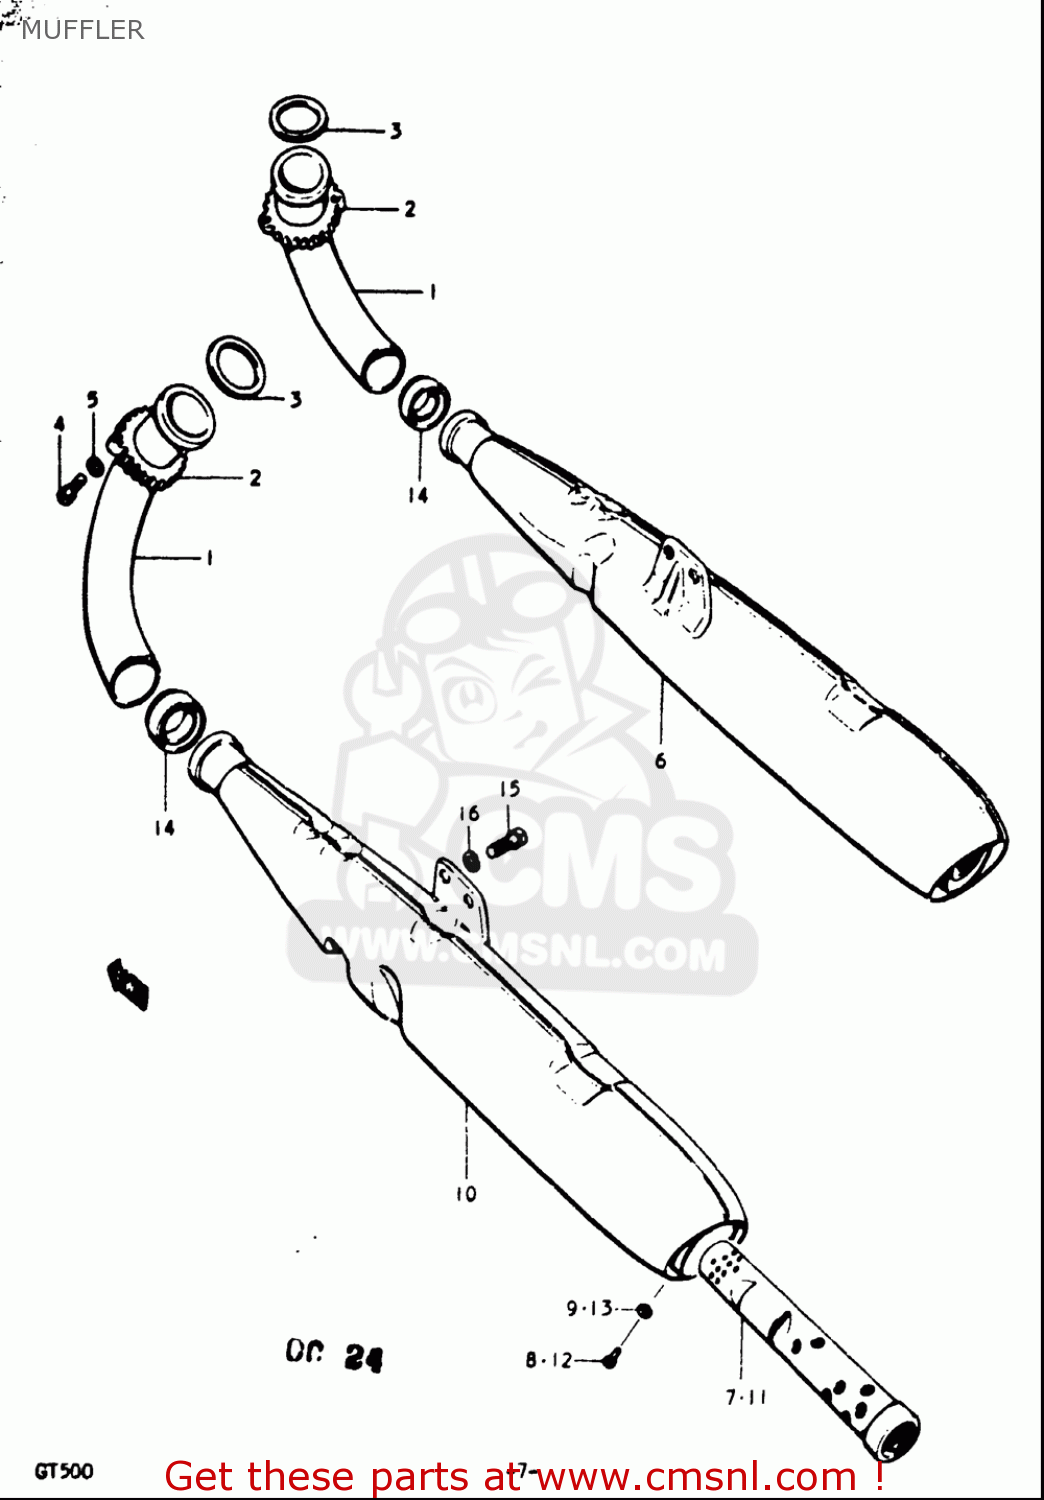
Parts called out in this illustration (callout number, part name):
1	PIPE,EXHAUST
3	GASKET,EXHAUST PIPE (NAS)
4	BOLT
5	WASHER,LOCK
7	PIPE,BAFFLE
8	BOLT(5X8)
9	WASHER,LOCK
11	PIPE,BAFFLE
12	BOLT(5X8)
13	WASHER,LOCK
14	CONNECTOR,MUFFLER
15	BOLT
16	WASHER,LOCK
